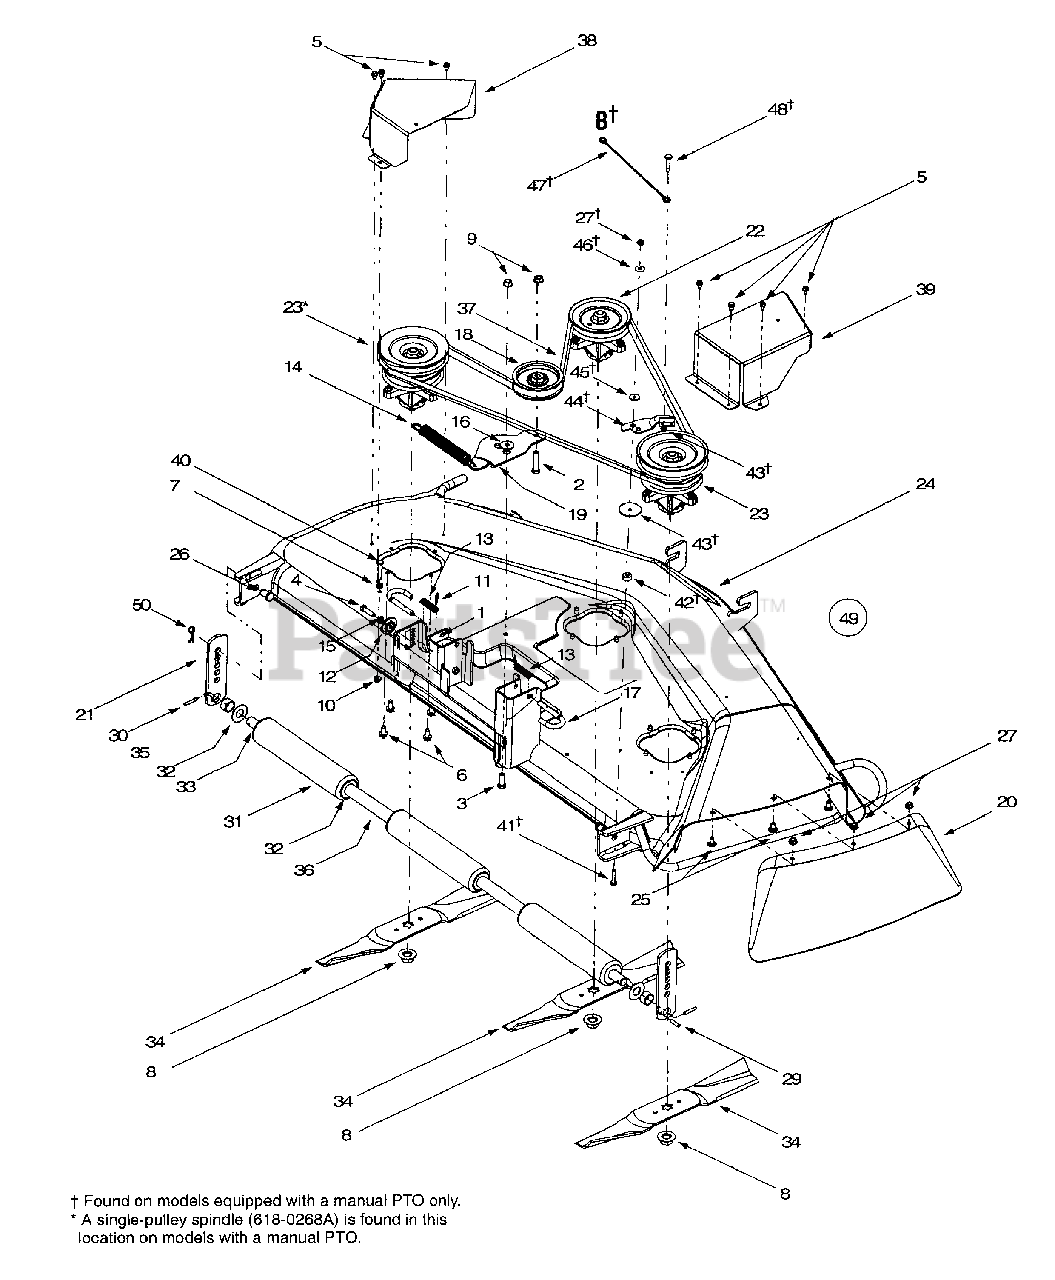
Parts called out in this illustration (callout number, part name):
1	Carriage Screw, 114 20 x .5
2	Hex Cap Screw, 3/8-16 x 1.75
3	Hex Cap Screw, 3/8-16 x 1.0
4	Hex Cap Screw, 5/16-18 x 1.25
5	Self Tapping Screw, 1/4-20 x .5
6	Self Tapping Screw, 5/16-18 x .75
7	Center Lock Nut, 1/4-20
8	Hex Flange Nut, 5/8-18
9	Flange Lock Nut, 3/8-16
10	Hex Flange Lock Nut, 1/4-20
11	Internal Cotter Pin, .072 x 1.12
12	Deck Adjustment Gear
13	Compression Spring, .406 x .531 x 1.75
14	Extension Spring, .91 x 7.33
15	Lock Washer, 5/16
16	Shoulder Spacer, .625 x .169
17	Deck Release Pin
18	Flat Idler Pulley, 3.5 OD
22	Center Spindle Assembly, 5 Dia.
23	Double Pulley Spindle Assembly
26	Clevis Pin, .50 Dia. x .78
27	Hex Flange Lock Nut, 5/16-18 (Grade 5)
29	Spring Pin, 1/4 Dia. x 1
30	Spring Pin, 3/16 x 1.25
31	Deck Roller
32	Flat Washer, .78 x 1.59 x .06
33	Deck Roller Shaft, .75 Dia. x 47.12
34	Blade, Star Center, 17.3
35	Spacer, .752 x 1.0 x .53
41	Hex Cap Screw, 5/16-18 x 1.5
42	Spacer, .34 x .87 x .44
43	Flat Washer, .34 x 2.5 x .10
44	Deck Brake Assembly
45	Shoulder Spacer
46	Bell Washer, .325 x .930 x .045
47	Bracket Cable, 12"
48	Shoulder Screw, .374 x 1.16
